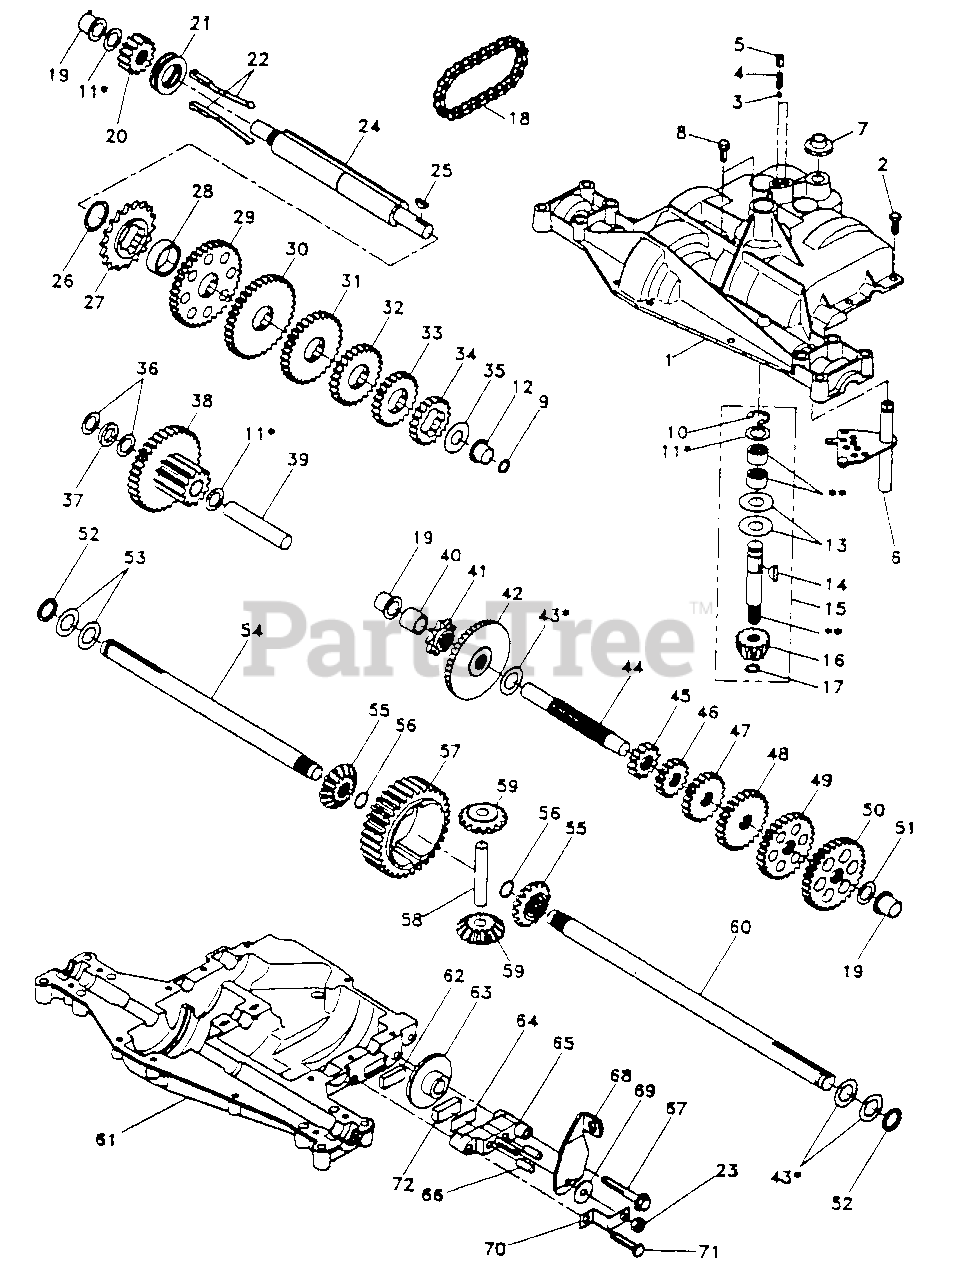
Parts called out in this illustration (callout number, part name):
1	Housing, Upper (AYP part number)
2	Screw, Self-Tapping, Large 1/4-20 x .734 (AYP part number)
3	Ball, Detent (AYP part number)
4	Spring, Detent (AYP part number)
5	Screw, Set (AYP part number)
6	Kit, Shifter Assembly (AYP part number)
7	Boot, Shifter (AYP part number)
8	Screw, Self-Tapping, with Sealer (AYP part number)
9	Square Ring (AYP part number)
10	Ring, Retaining (AYP part number)
11	Assembly, Kit, Shim .625 Shaft (AYP part number)
12	Bearing, Flange (AYP part number)
13	Washer, Plain .632 x 1.38 x .046 (AYP part number)
14	Key, Woodruff, #9 (AYP part number)
15	Assembly, Kit, Input Shaft (AYP part number)
16	Pinion, Bevel, 14 Teeth (AYP part number)
17	Ring, Retaining (AYP part number)
18	Chain, 24 Pitches (AYP part number)
19	Bearing, Flange (AYP part number)
20	Gear, Spur, 14 Teeth (AYP part number)
21	Collar, Clutch (AYP part number)
22	Assembly, Kit, Clutch Keys (AYP part number)
23	Locknut 5/16-24 (AYP part number)
24	Shaft, Intermediate (AYP part number)
25	Key, Woodruff, #61 (AYP part number)
26	Ring, Retaining (AYP part number)
27	Sprocket, 18 Teeth (AYP part number)
28	Spacer (AYP part number)
29	Gear, Spur, 37 Teeth (AYP part number)
30	Gear, Spur, 35 Teeth (AYP part number)
31	Gear, Spur, 30 Teeth (AYP part number)
32	Gear, Spur, 25 Teeth (AYP part number)
33	Gear, Spur, 22 Teeth (AYP part number)
34	Gear, Spur, 19 Teeth (AYP part number)
35	Washer, Plain .640 x 1.37 x .061 (AYP part number)
36	Washer, Plain .632 x 1.00 x .026 (AYP part number)
37	Spacer .630 x 1.00 x .169 (AYP part number)
38	Assembly, Gear, Combination of 12 Teeth and 35 Teeth (AYP part number)
39	Shaft, Idler (AYP part number)
40	Spacer .635 x .875 x .755 (AYP part number)
41	Sprocket, 9 Teeth (AYP part number)
42	Gear, Bevel, 42 Teeth (AYP part number)
43	Assembly, Kit, Shim .750 Shaft (AYP part number)
44	Shaft, Drive (AYP part number)
45	Gear, Spur, 12 Teeth (AYP part number)
46	Gear, Spur, 15 Teeth (AYP part number)
47	Gear, Spur, 20 Teeth (AYP part number)
48	Gear, Spur, 25 Teeth (AYP part number)
49	Gear, Spur, 28 Teeth (AYP part number)
50	Gear, Spur, 31 Teeth (AYP part number)
51	Washer, Plain .632 x 1.00 x .060 (AYP part number)
52	Washer, Neoprene (AYP part number)
53	Washer, Plain .758 x 1.25 x .031 (AYP part number)
54	Axle, L.H. (AYP part number)
55	Gear, Miter, 15 Teeth (AYP part number)
56	Ring, Retaining (AYP part number)
57	Gear, Spur, 32 Teeth (AYP part number)
58	Shaft, Cross (AYP part number)
59	Gear, Miter, 15 Teeth (AYP part number)
60	Axle, R.H. (AYP part number)
61	Housing, Lower (AYP part number)
62	Puck, Friction (AYP part number)
63	Disc, Brake (AYP part number)
64	Spacer (AYP part number)
65	Jaw, Brake (AYP part number)
66	Pin, Dowel (AYP part number)
67	Screw, Self-Tapping, Large 5/16-18 x 2.25 (AYP part number)
68	Lever, Actuating (AYP part number)
69	Washer, Plain .321 x 1.00 x .055 (AYP part number)
70	Bracket, Anti-Rotation (AYP part number)
71	Screw, Self-Tapping, Large 5/16-18 x 1.44 (AYP part number)
72	Puck, Friction (AYP part number)
73	Grease (AYP part number)
